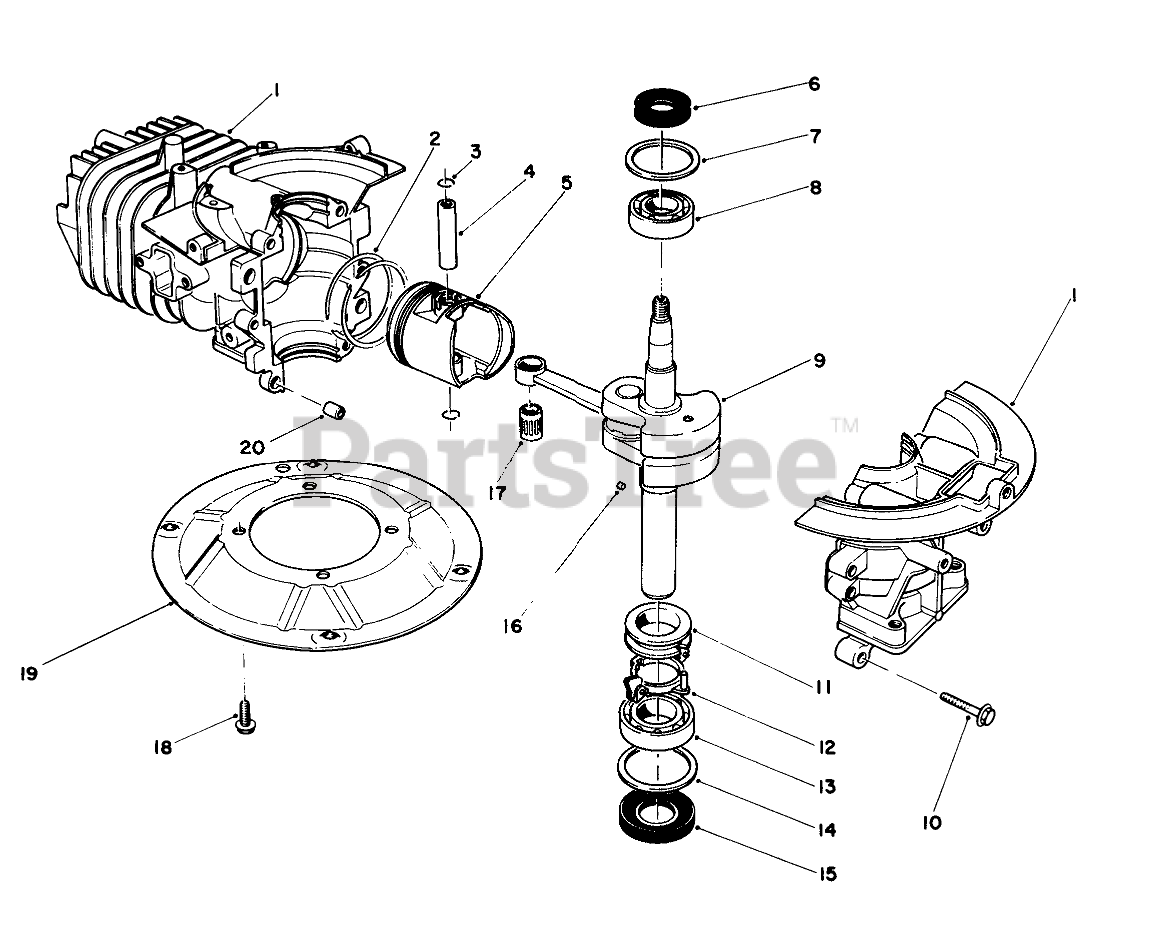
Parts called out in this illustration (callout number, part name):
1	CRANKCASE
2	RING SET
4	PIN-PISTON
5	Piston
6	OIL SEAL
7	WASHER-UPPER
8	BEARING-UPPER
9	Pin-Wrist
11	SPACER
12	BRACKET
13	LOWER BRG
14	WASHER-LOWER
15	SEAL-OIL
17	BEARING
19	PLATE-MOUNTING
